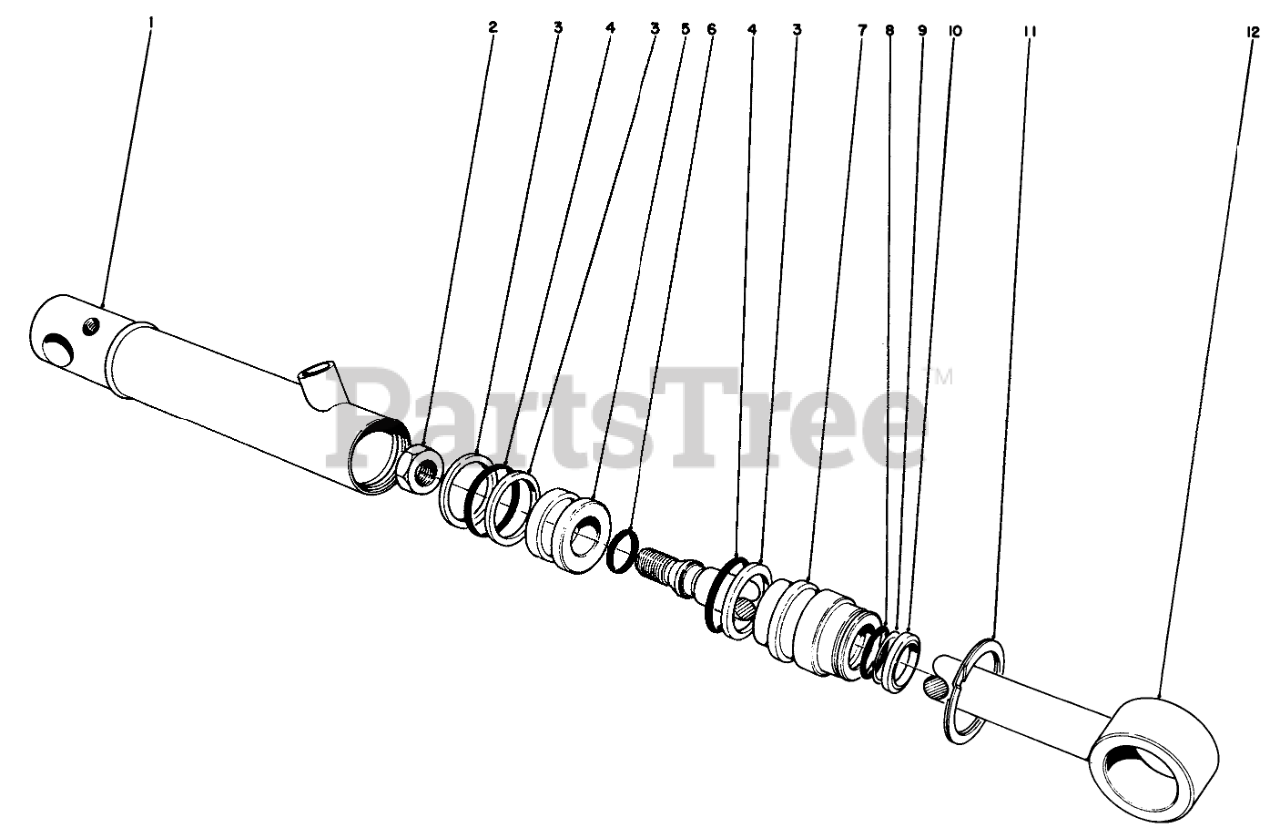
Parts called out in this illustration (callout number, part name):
1	Tube Assembly
2	Nut
3	Back Up Washer
4	O-Ring Piston
5	PISTON
9	Leather
10	Dust Seal
11	RING-RETAINING
12	SHAFT W/CLEVIS
